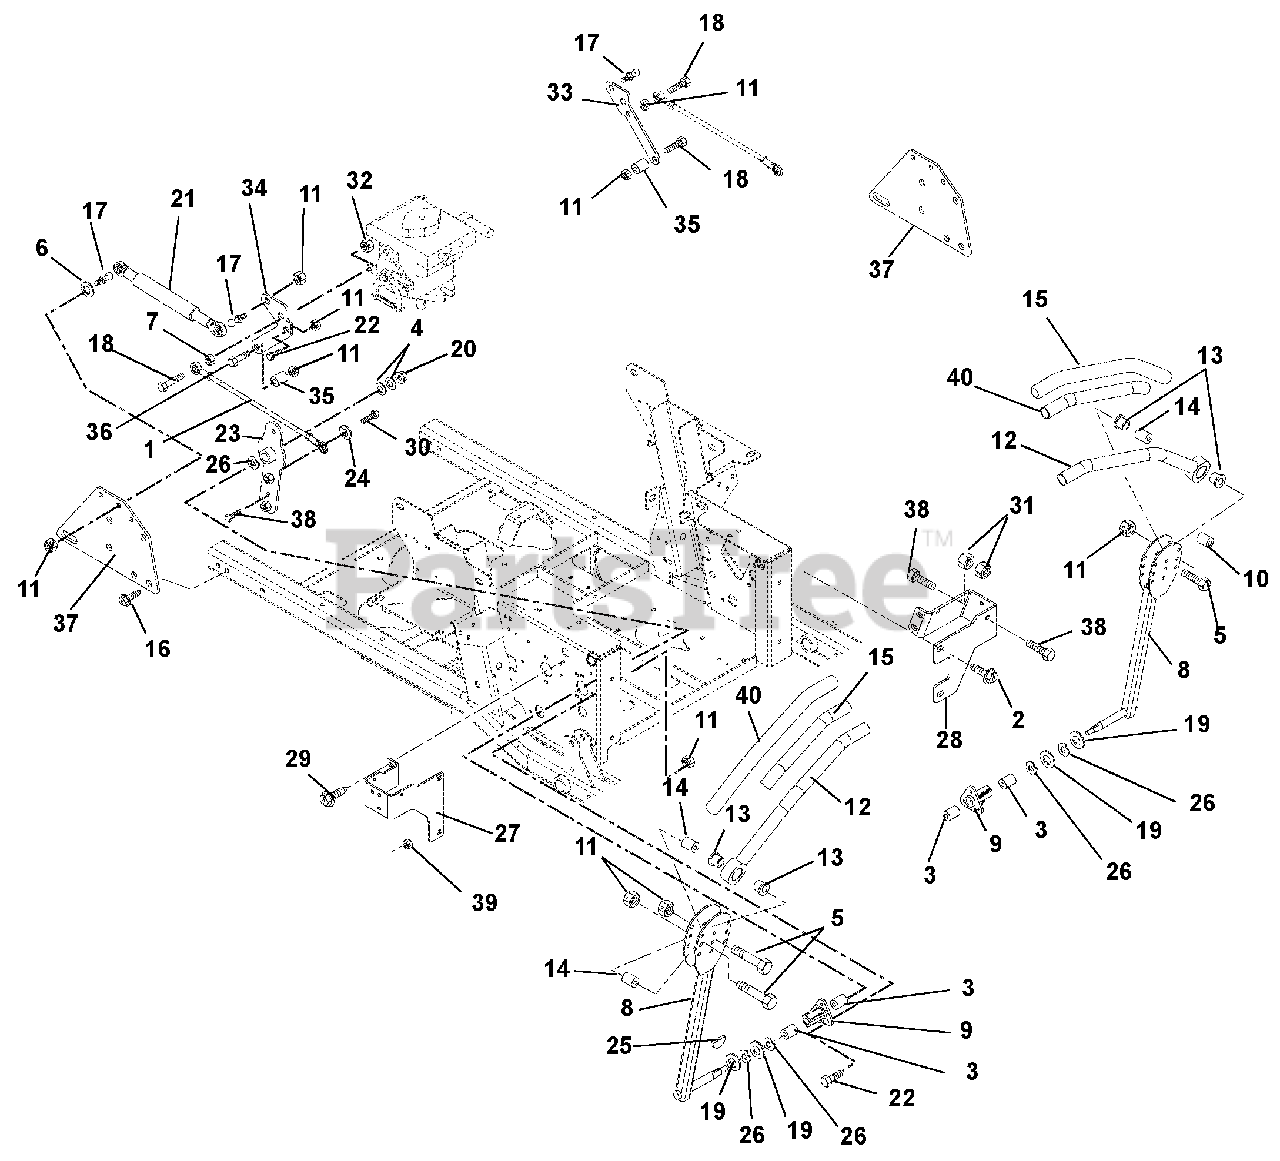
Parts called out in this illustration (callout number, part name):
1	Assembly, Steering Rod .38 Rod x 7.60
2	Screw, Tapping .38-16 x .75 Hex Washer Head
3	Bushing .625 x .75 x .50
4	Washer, Flat Steel .403 x .812 x .065
5	Bolt, Hex .31-18 x 1.75 Grade 5
6	Washer, Flat Steel .344 x .688 x .065
7	Nut, Hex .38-16
8	Control Arm
9	Bushing, Flange
10	Bushing, Eccentric .31 x .75 x .97
11	Nut, Locking Top Flange .31-18
12	Handle Weldment Left Hand
12	Handle Weldment Right Hand
13	Bushing, Flange Nylon .762 x 1.48 x .44
15	Grip, Handlebar
16	Screw, Tapping .31-18 x .50 Hex Washer Head
17	Stud, Ball
18	Bolt, Hex .38-16 x 1.50 Grade 5
19	Washer, Flat Steel .63 x 1.005 x .062
20	Nut, Locking Top Flange .38-16
21	Damper, Stabilus
22	Bolt, Hex .31-18 x .75 Grade 5
23	Weldment, Pivot Arm
24	Washer, Locking .38 x .094 Regular
25	Key, Woodruff .13 x .63
26	Washer, Wave
27	Stop, Steering Right Hand
28	Stop, Steering Left Hand
29	Screw, Tapping .38-16 x .50 Hex Washer Head
30	Bolt, Hex .38-16 x 1.25 Grade 5
31	Nut, Hex Jam .375-16
32	Nut, Locking Center .38-16
33	Bracket, Left Hand
34	Bracket, Right Hand
35	Spacer .318 x .43 x .375
36	Bolt, Hex .31-18 x 1.25 Grade 5
37	Bracket, Damper
38	Bolt, Hex .375-16 x 1.75 Full Thread
39	Nut, Locking Top Flange .25-20
40	Tube, .88ID x 1.00OD x 10.75
